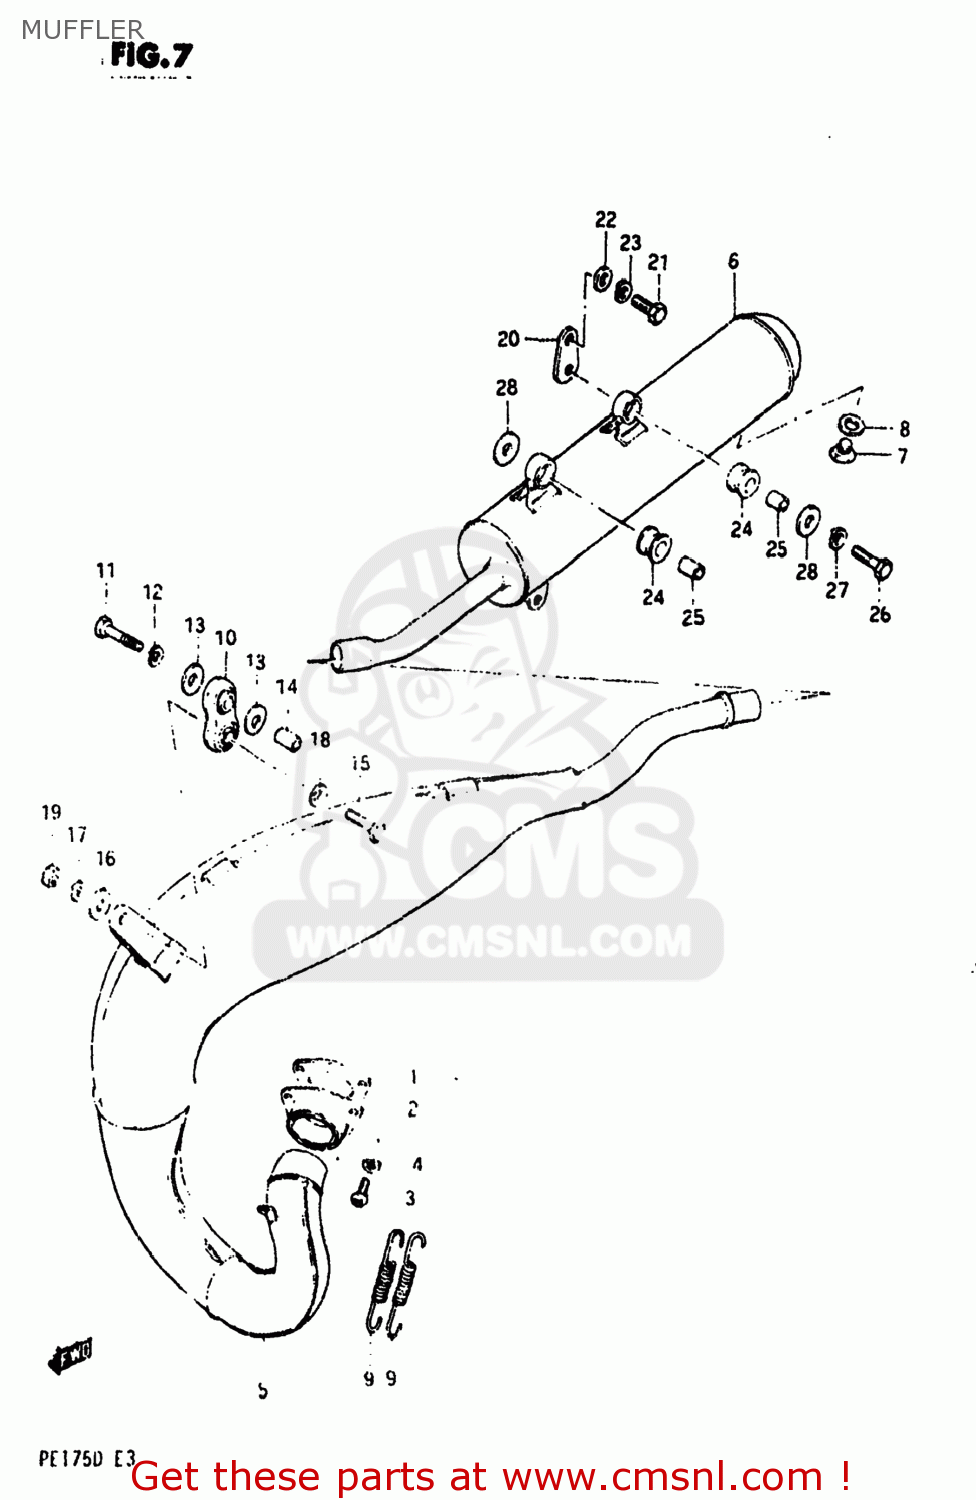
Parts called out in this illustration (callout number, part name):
1	GASKET,EXHAUST PIPE (MCA)
2	FLANGE,EXHAUST PIPE
3	SCREW
4	LOCK WASHER
5	BODY,MUFFLER
6	MUFFLER ASSEMBLY
7	PLUG(12X9)
8	GASKET(12.1X16.2X3.7) (NAS)
9	SPRING
10	DAMPER,MUFFLER
11	BOLT 8X50
12	LOCK WASHER
13	WASHER
14	SPACER (8.2X12X17)
15	BOLT
16	WASHER
17	LOCK WASHER
18	WASHER
19	NUT
20	BRACE,MUFFLER,REAR
21	BOLT
22	WASHER
23	LOCK WASHER
24	CUSHION
25	SPACER (8.2X12X17)
26	BOLT
27	LOCK WASHER
28	WASHER (8.5X29X1.6)
